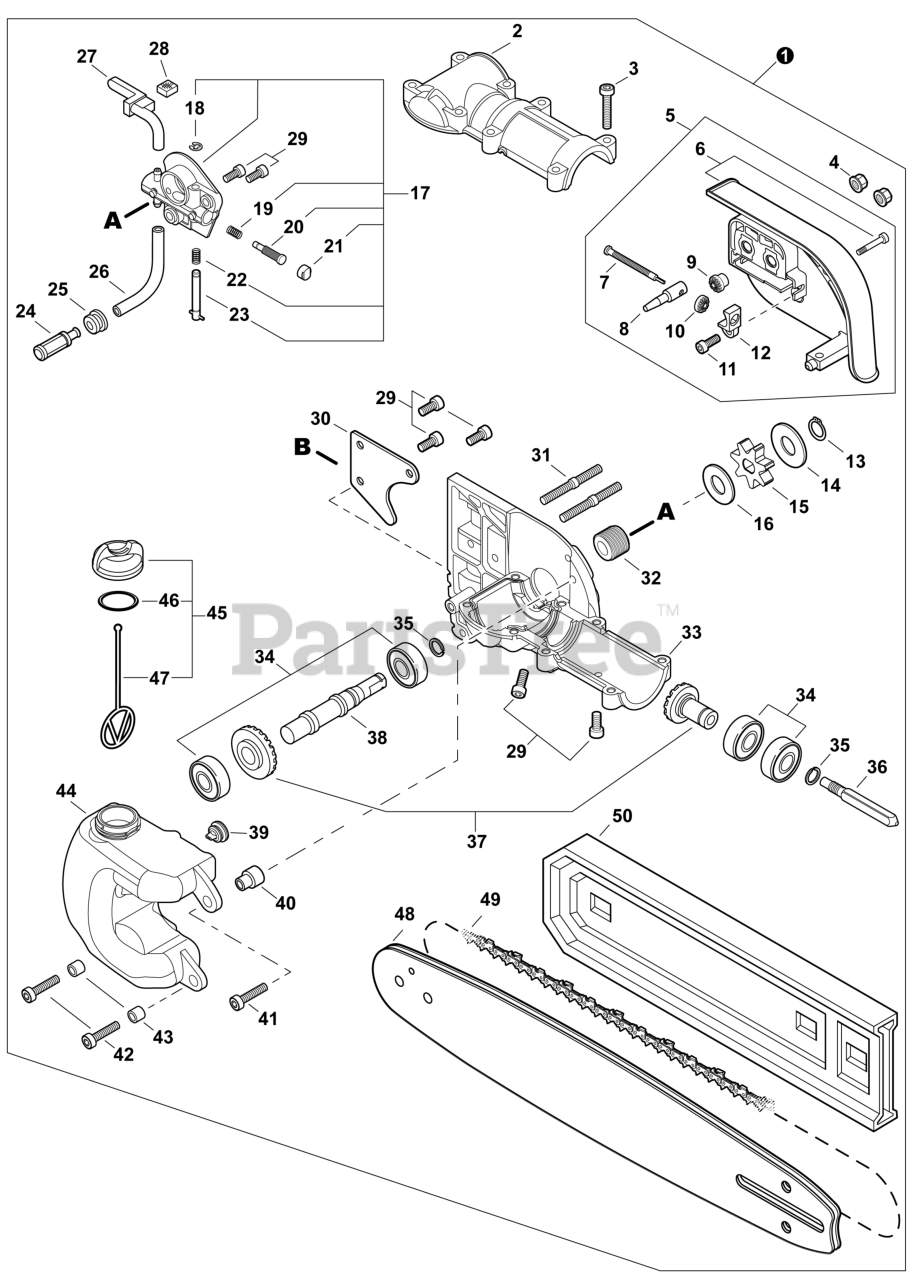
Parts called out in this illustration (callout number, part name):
1	GEAR CASE ASSY
2	COVER, GEAR CASE
3	BOLT, TORX 5x25
4	NUT, FLANGE M6
5	SPROCKET GUARD ASSY
6	GUARD, SPROCKET
7	BOLT 5
8	TENSIONER, CHAIN
9	GEAR - 14 TOOTH
10	GEAR - 14 TOOTH
11	SCREW 4
12	COLLAR 8
13	RING, SNAP
14	WASHER 10
15	SPROCKET, DRIVE
16	WASHER 10
17	AUTO-OILER ASSY
18	E-RING
19	SPRING
20	PLUNGER ASSY
21	CAP, PLUNGER
22	SPRING
23	ADJUSTER, OILER
24	FILTER, OIL
25	GROMMET
26	PIPE 3x6x70
27	PIPE, OIL OUTLET
28	PAD, FOAM
29	BOLT, TORX 5x10
30	HOOK
31	BOLT, STUD 6
32	GEAR, WORM
33	CASE, GEAR
34	BEARING, BALL
35	RING, SNAP 12
36	CONNECTOR, DRIVESHAFT
37	GEAR SET, BEVEL
38	SHAFT, GEAR
39	VENT ASSY
40	COLLAR 6
41	BOLT, TORX 5x25
42	BOLT, TORX 5x20
43	SPACER 6.2x7.8x6
44	TANK, OIL
45	CAP ASSY
46	O-RING 18
47	CONNECTOR, CAP L= 60 MM
48	GUIDE BAR, 12" 0.043" GA
49	SAW CHAIN 12"
50	SCABBARD 12" RED
